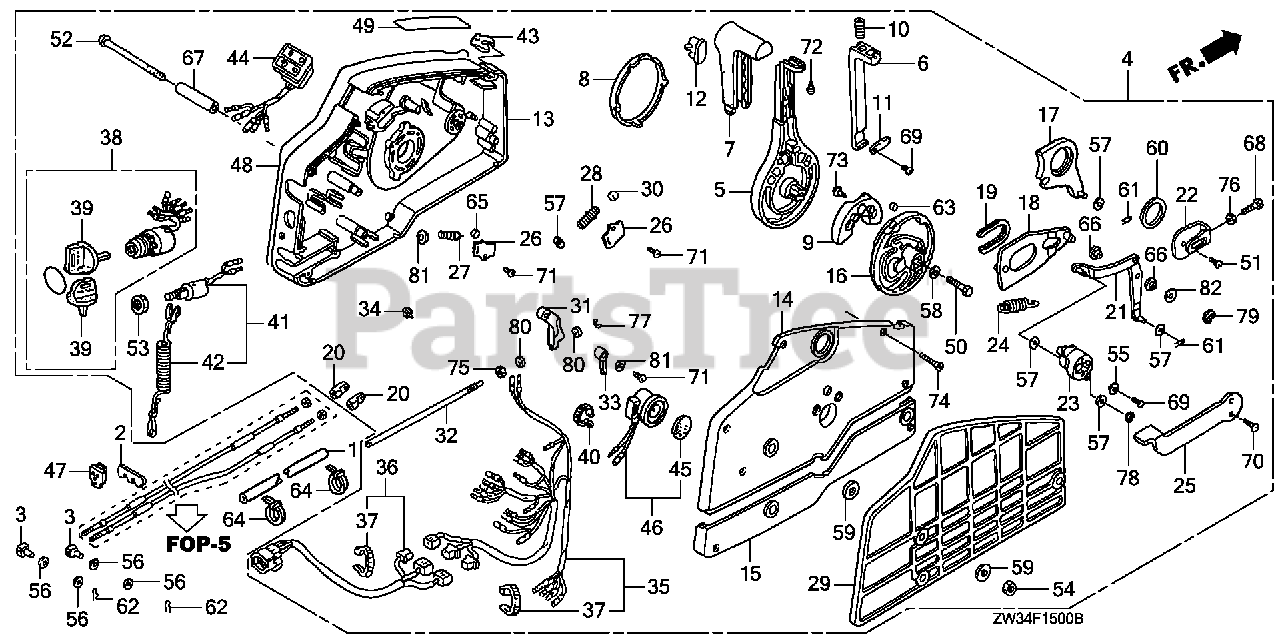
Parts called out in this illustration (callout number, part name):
2	PLATE, REMOTE CONTROL CABLE
3	PIVOT, SHIFT
4	S/R SW 2 LIGH MAN TL
5	HANDLE, REMOTE CONTROL
6	LEVER, HANDLE LOCK
7	GRIP, REMOTE CONTROL HANDLE
8	CAP, HANDLE
9	BLOCK, NEUTRAL LOCK
10	SPRING, REMOTE CONTROL HANDLE
11	PLATE, LEVER SETTING
12	COVER, GRIP
13	HOUSING, REMOTE CONTROL BOX (A)
14	HOUSING, REMOTE CONTROL BOX (B)
15	HOUSING, REMOTE CONTROL BOX (C )
16	WHEEL, CONTROL
17	ARM, SHIFT LINK
18	PLATE, SLIDING
19	COLLAR, SLIDING PLATE
20	PIVOT, SHIFT
21	ARM, LINK JOINT
22	BRACKET, LINK JOINT
23	WHEEL, ACCELERATOR
24	SPRING, ACCELERATOR WHEEL
25	LEVER, IDLE
26	PLATE, SPRING SETTING
27	SPRING, SHIFT CLICK
28	SPRING, CHOKE RETURN
29	SPACER, REMOTE CONTROL BOX
30	SPACER, CLICK SPRING
31	BLOCK, THROTTLE FRICTION
32	BOLT, FRICTION
33	SPACER, NEUTRAL SWITCH
34	SPACER, CABLE CLAMP
35	CABLE ASSY., REMOTE CONTROL (B) Use from Frame SN 1300029.
36	CABLE ASSY., SWITCH PANEL
37	TIE, CABLE (NATURAL 2.4X92) Use up to Frame SN 1300359.
38	SWITCH ASSY., COMBINATION DUAL QTY = (2) (SINGLE)
39	KEY ASSY., COMBINATION SWITCH (35100-ZV5-003 ONLY) DUAL QTY = (4) (SINGLE)
40	BAND (BLACK 3.5X140)
41	SWITCH ASSY., EMERGENCY STOP
42	WIRE, EMERGENCY (SINGLE) (DUAL)
43	CLIP, EMERGENCY LOCK
44	LAMP ASSY., INDICATION (2-LED)
45	PLATE, TURN SIGNAL BUZZER DUAL QTY = (2) (SINGLE)
46	BUZZER, WARNING DUAL QTY = (2) (SINGLE)
48	PLATE, REMOTE CONTROL (CAUTION=SILVER)
49	MARK, FAST IDLE
50	BOLT, FLANGE (8X35) Use from Frame SN 4800713.
51	SCREW, PAN (6X10)
52	SCREW (6X95)
53	NUT, HEX. (16MM) DUAL QTY = (2) (SINGLE)
54	NUT, HEX. (6MM)
55	WASHER, PLAIN (5MM)
57	WASHER, PLAIN (6MM) Use from Frame SN 4800713.
59	WASHER (6MM)
60	WASHER (28MM)
61	PIN, LOCK (6MM)
63	PIN (6X6)
65	ROLLER, CLICK
66	COLLAR, LINK JOINT
67	COLLAR, DISTANCE (6X10X43.5)
68	BOLT, HEX. (5X16)
69	SCREW, PAN (5X10)
70	SCREW, FLAT (5X12) Use from Frame SN 4800713.
71	SCREW, TAPPING (5X10)
72	SCREW, TAPPING (5X12)
73	SCREW, TAPPING (6X16)
74	SCREW, TAPPING (5X25)
75	NUT, HEX. (6MM)
76	NUT, HEX. (5MM)
77	E-RING (3MM)
78	E-RING (4MM)
79	E-RING (7MM)
80	WASHER, PLAIN (4MM) Use from Frame SN 4800713.
81	WASHER, PLAIN (5MM)
82	WASHER, PLAIN (8MM) Use from Frame SN 4800713.
